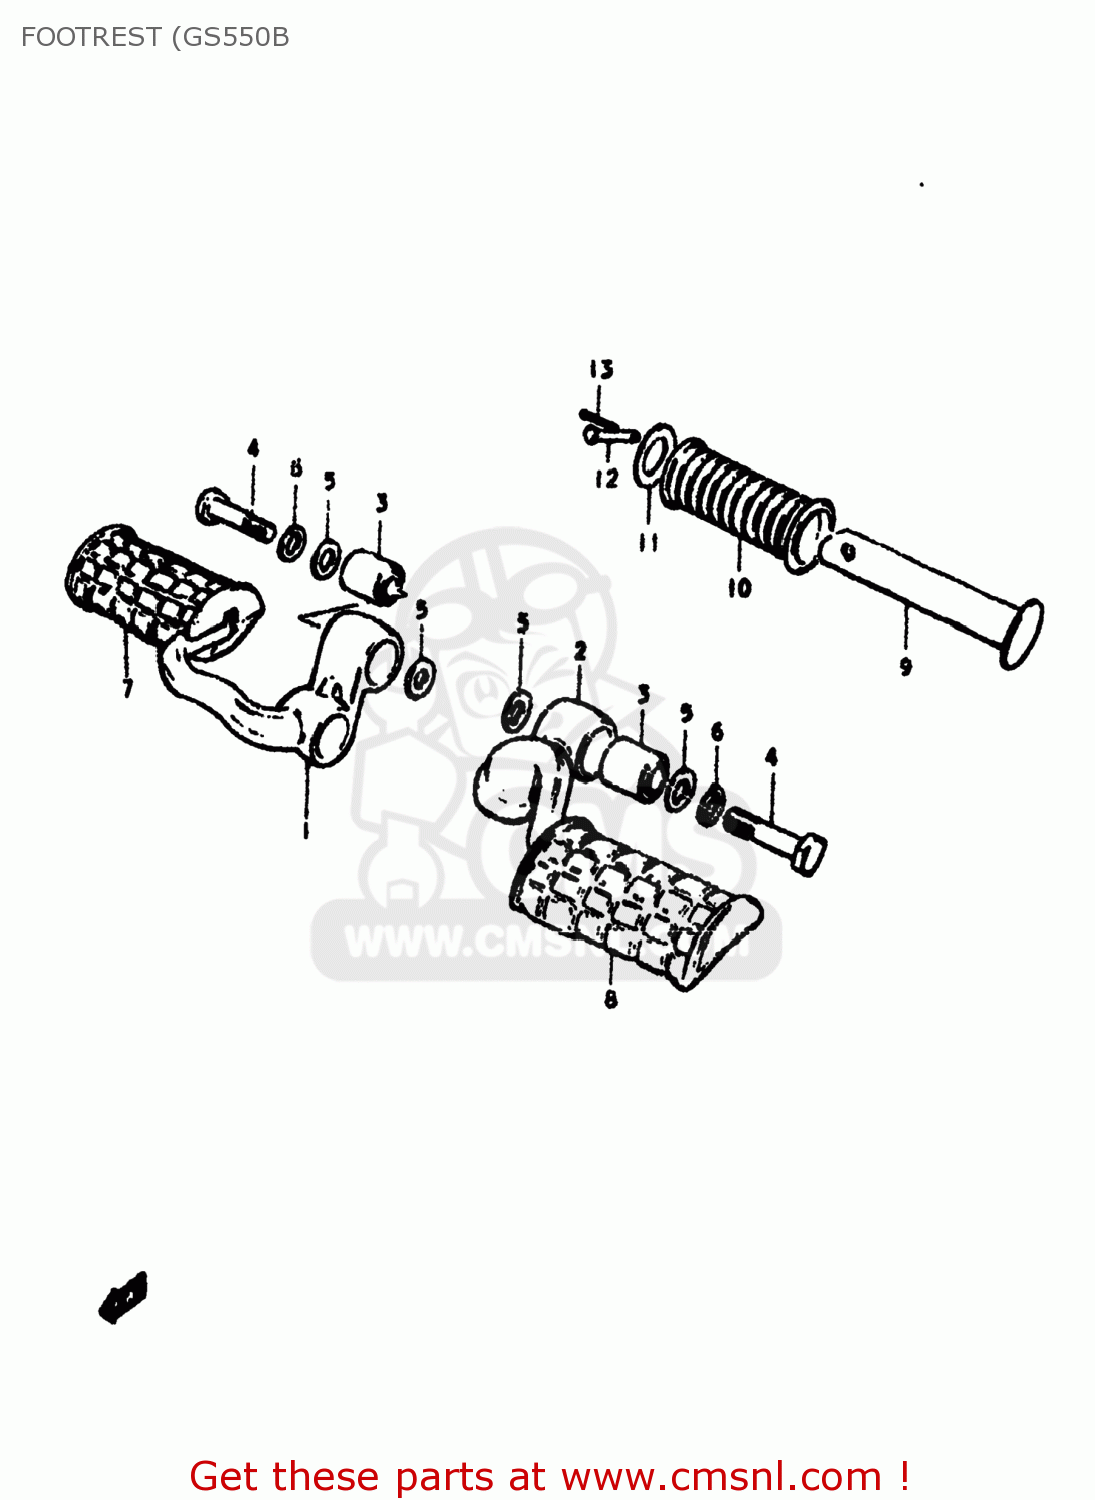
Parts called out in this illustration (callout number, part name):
1	BAR,FRONT FOOTREST
2	BRACKET,FOOTREST,LEFT
3	BUSH
4	BOLT
5	WASHER (10.1X21X2.3)
6	LOCK WASHER
7	RUBBER,FR FOOTREST,R
8	RUBBER,FOOTREST
9	BAR,FOOTREST RUBBER
10	RUBBER,REAR FOOTREST
11	WASHER (19.5X32X2)
12	PIN
13	PIN
